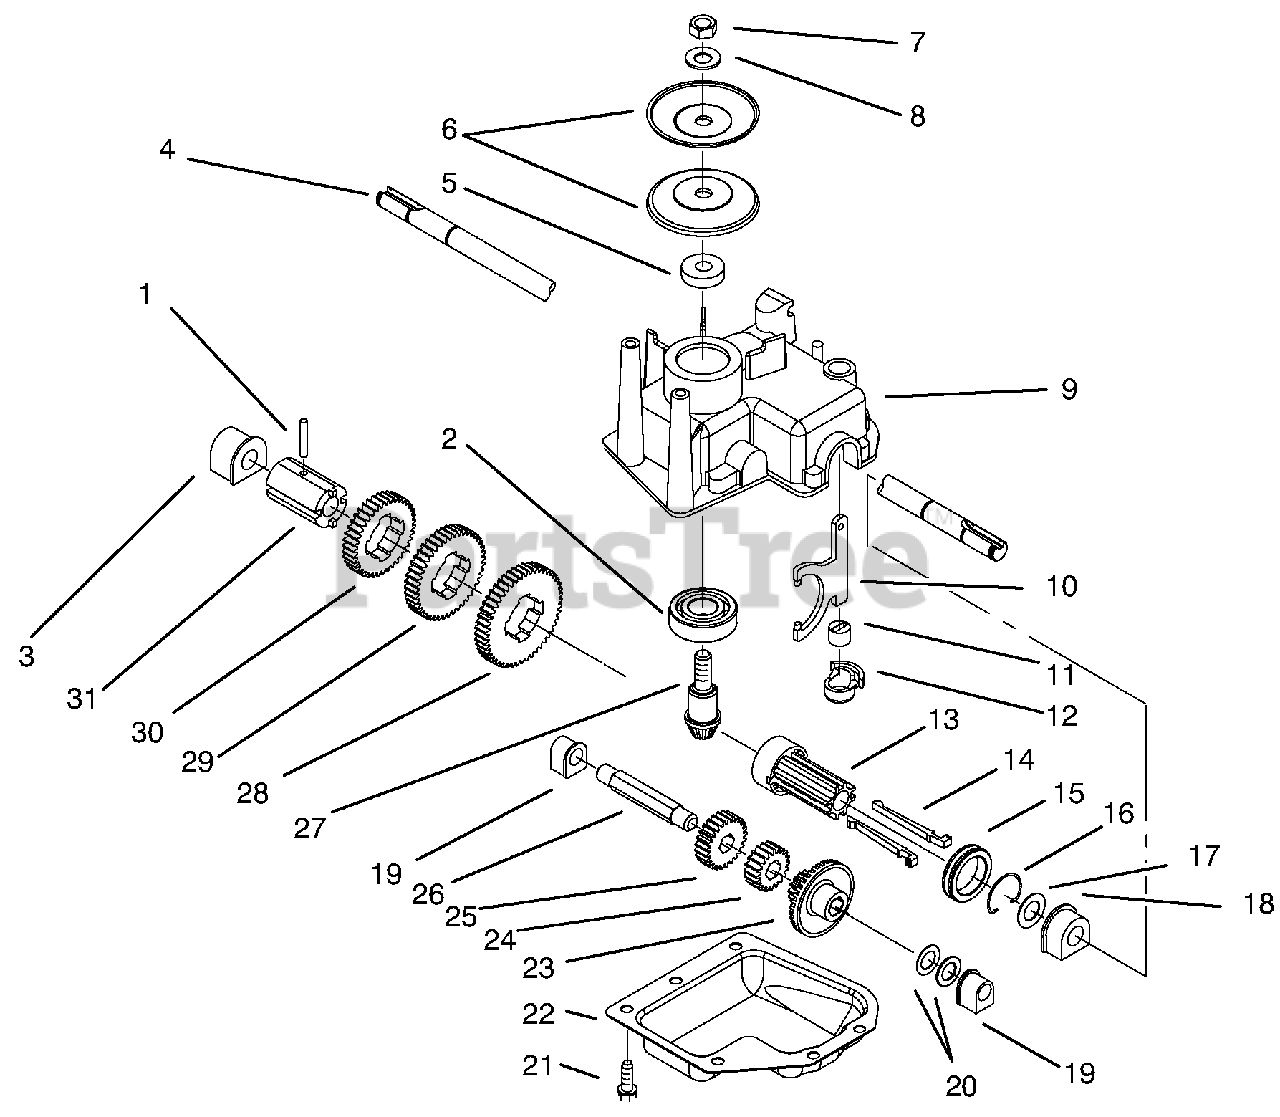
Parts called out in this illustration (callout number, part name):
1	Pin-Groove
2	Bearing-Ball
3	Bushing-Output
4	Shaft-Output
6	Pulley-Half
9	Gearcase-Upper
10	Yoke-Shift
11	Bushing-Yoke
12	Retainer-Shift Fork
13	Sleeve-Shift Key
14	Key-Shift
15	Collar-Shift
16	Clip-Spring
18	Bushing-Output
19	Bushing-Inter. Shaft
20	Washer-Thrust
22	Gear Case Cover
23	Pinion-15 Tooth
24	Pinion-20 Tooth
25	Pinion-25 Tooth
26	Shaft-Intermediate
27	Pinion-Bevel
28	Gear-49Tooth
29	Gear-44Tooth
30	Gear-39 Tooth
31	Sleeve-Gear
